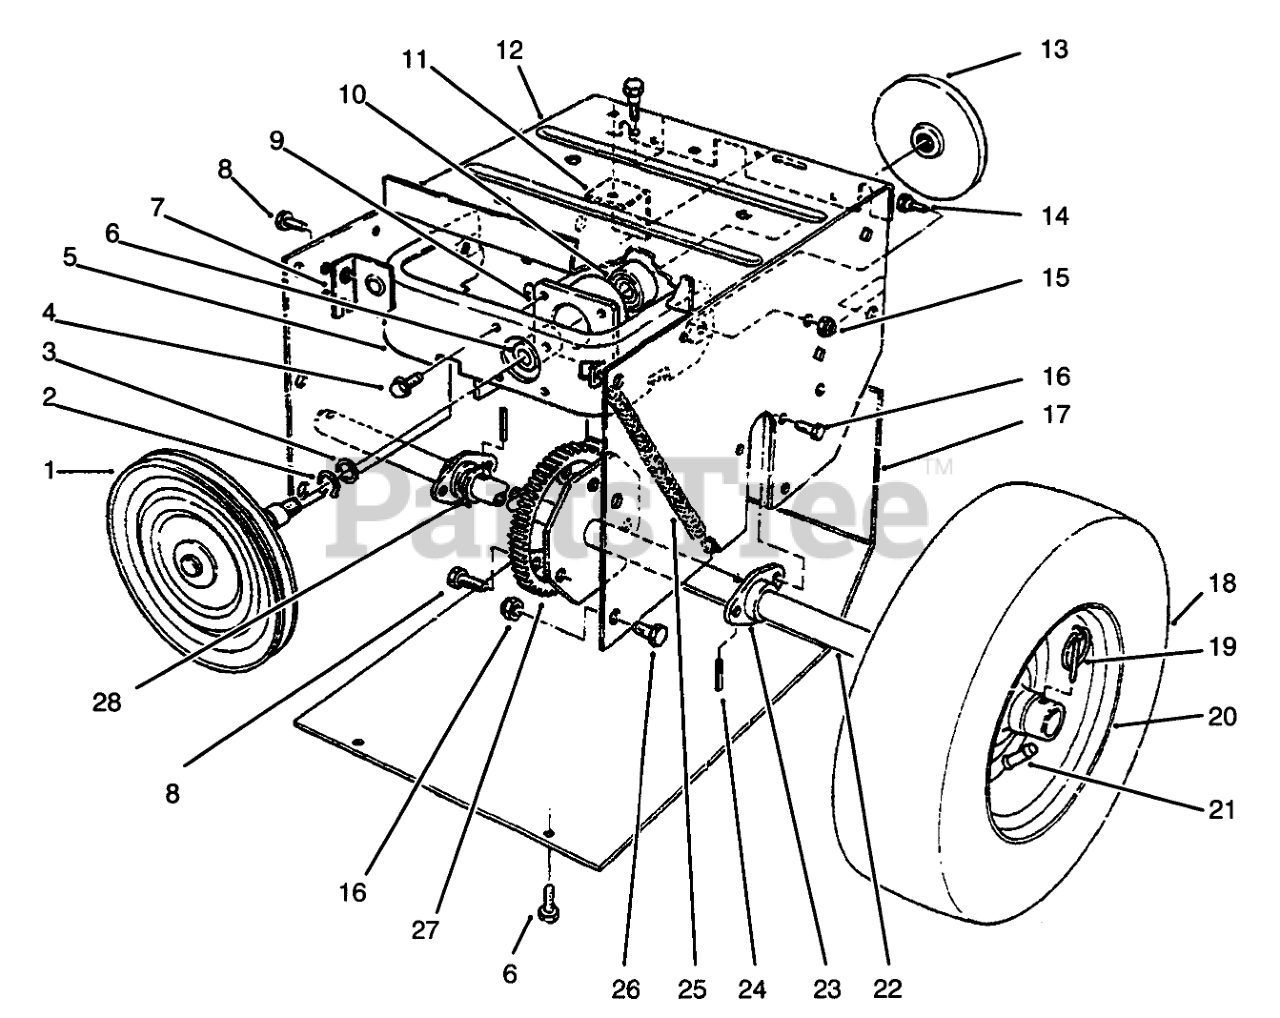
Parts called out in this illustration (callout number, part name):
1	PULLEY AND DRIVE ASM
2	RING-RETAINING, EXT
3	WASHER-THRUST
4	SCREW
5	Frame-Friction Plate
6	BUSHING
7	BRACKET-MOUNT, FRONT
8	SCREW-HWHTF
9	HUB-FRAME, TRACTION
10	BEARING-BALL
11	BRACKET-MOUNT, REAR
12	Frame-Traction
13	PLATE-FRICTION
14	BOLT-SHOULDER
15	NUT-LOCK, NI
16	SCREW-HWH
17	Bottom Cover
19	PIN-LYNCH
20	RIM-WHEEL
21	TUBE-INNER
22	SHAFT-AXLE
23	BEARING-AXLE
24	PIN-SPRING
25	SPRING-PLATE, FRICTION
26	SCREW-HH
27	GEAR-AXLE
28	WASHER-THRUST
